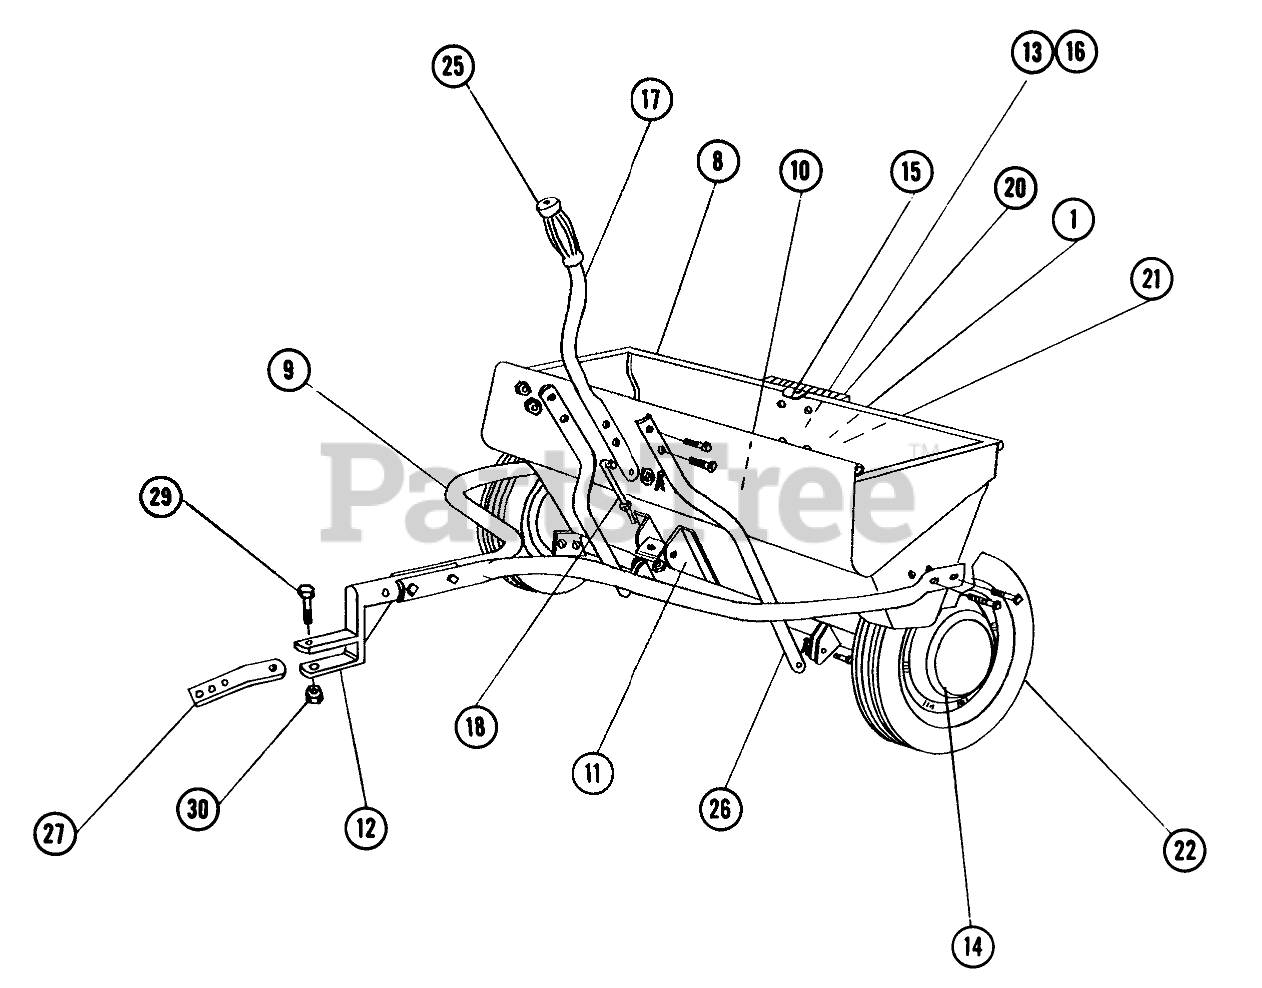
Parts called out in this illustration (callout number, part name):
1	Spring-Control Rod
2	Agitator-R.H.
3	Agitator-L.H.
4	Baffle
5	Ranger Shut-Off Bar
6	Shut-Off Bar
7	Bearing Support Ass-y. with Bearing
8	Hopper
9	Hitch Brace
10	Brace-Hopper
11	Pivot-Bracket Ass-y.
12	Hitch
13	Housing-Control Ass-y. (Less Knob)
14	Hub Cap
15	Pointer
16	Knob
17	Operating Lever with Grip
18	Pivot Link Rod
19	Bearing End Plate
20	Scale Mark Plate
21	Rod-Rate Control
22	Wheel with Tire
23	Bearing
24	Carton
25	Handle Grip
26	Shut Off Brace
30	Nut
